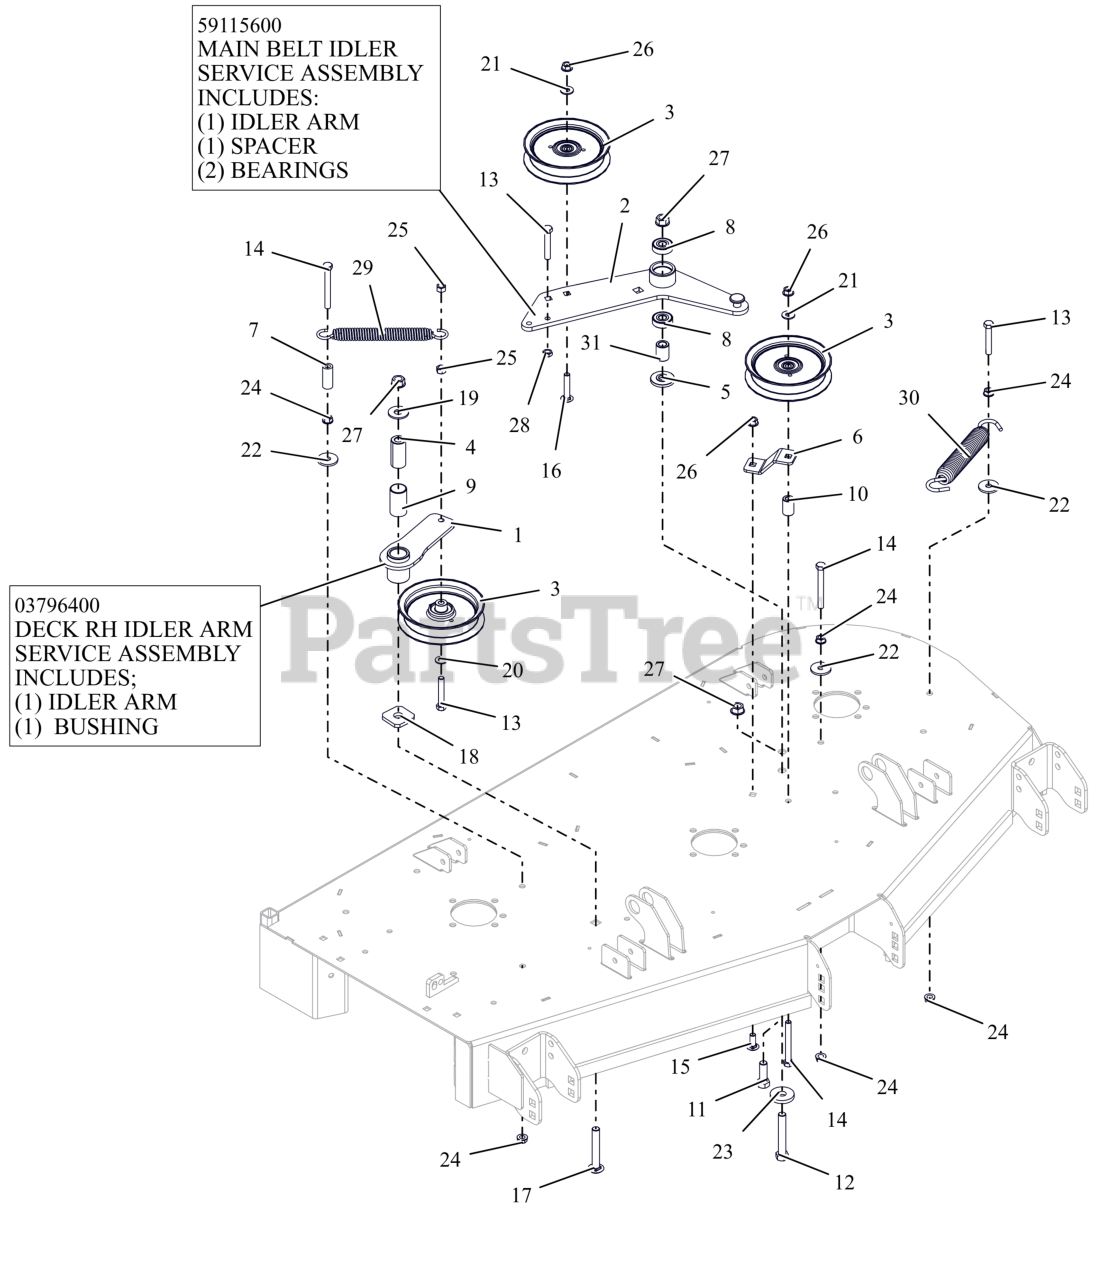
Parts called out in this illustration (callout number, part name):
1	WMT, IDLER ARM - BLACK
1	ASM, IDLER ARM (DECK)
2	WLDMT, DECK PTO IDLR ARM
2	ASSEMBLY, MAIN BELT IDLER
3	IDLER, FLAT 5.00"
4	BSHG, SPCR .502X.997X2.03 PM
5	SPACER, IDLER ARM
6	PTO FIXED IDLER MTG BRKT-ORG
7	HOSE, .38 X 1.65
8	BRG-BALL .500X1.38X.437
9	BSHG, 1.00X1.125X1.937
10	BUSHING, SLV .380X.750X1.190
11	BLT,HEX .50-13X1.50 G5 ZCC
12	BLT,HEX .50-13X3.25 G5 ZCC
13	BLT,HEX .38-16X2.25 G5 ZCC
14	BLT, HEX .38-16X3.25 G5 ZCC
15	BLT,RHSSN .38-16X1.00 G5 ZCC
16	BLT,RHSSN.375-16X2.00 G5 ZCC
17	BTL,RHSSN .500-13 X 3.25 G5 ZCC
18	WSHR-FLT .640X1.75X.250
19	WSHR,FLT .563X1.375X.109 ZCC
20	WSHR,FLT .406X.812X.065 ZCC
21	WSHR,FLT .375X.875X.083 ZCC
22	WSHR,FLT .406X1.375X.135 ZCC
23	WSHR-FL-STL 0.557X1.625X0.25 ZCC
24	NUT, SPNLK-FLG .38-16 G5 ZCC
25	NUT-LK-CTR .38-16 ZC120
26	NUT-LK-CTR-FLG .375-16 GF ZCC
27	NUT-LK-CTR-FLG .500-13 GG ZCC
28	NUT-JAM .375-16 G2 ZCC
29	SPRING, EXTENSION
30	SPRING, EXTENSION
31	SPACER .510 X .75 X 1.1485
